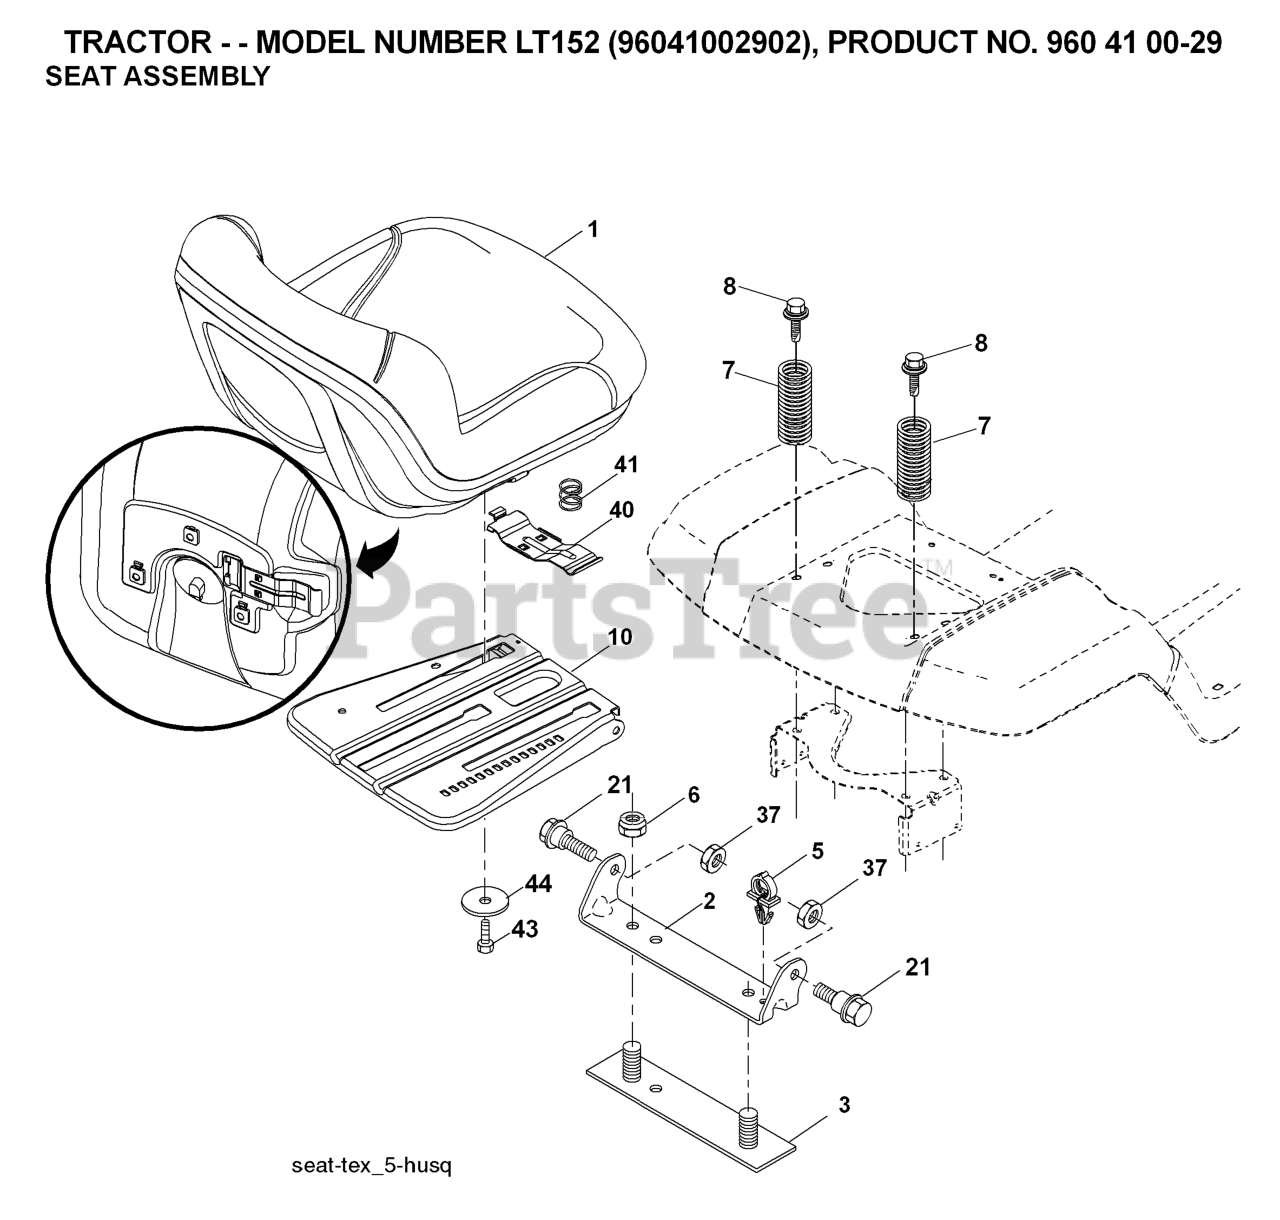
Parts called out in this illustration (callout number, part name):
1	SEAT.TH130.GRY.MILSCO.
2	BRKT.PIVOT.FENDER
3	STRAP
6	NUT
7	SPRING COMPRESSION
8	BOLT.5/16-18UNCX3/4 W/SEMS.BLK
10	PAN.ASM.SEAT.3PT
21	BOLT.SHOULDER.5/16-18
37	NUT.71038.31-18.HEX.NYLOCK
40	HANDLE.SLIDE.SEAT.TEX.BLACK
41	SPRING.LATCH.SEAT.TEX
44	WASHER 13/32 X 2-3/8 X 12GA
